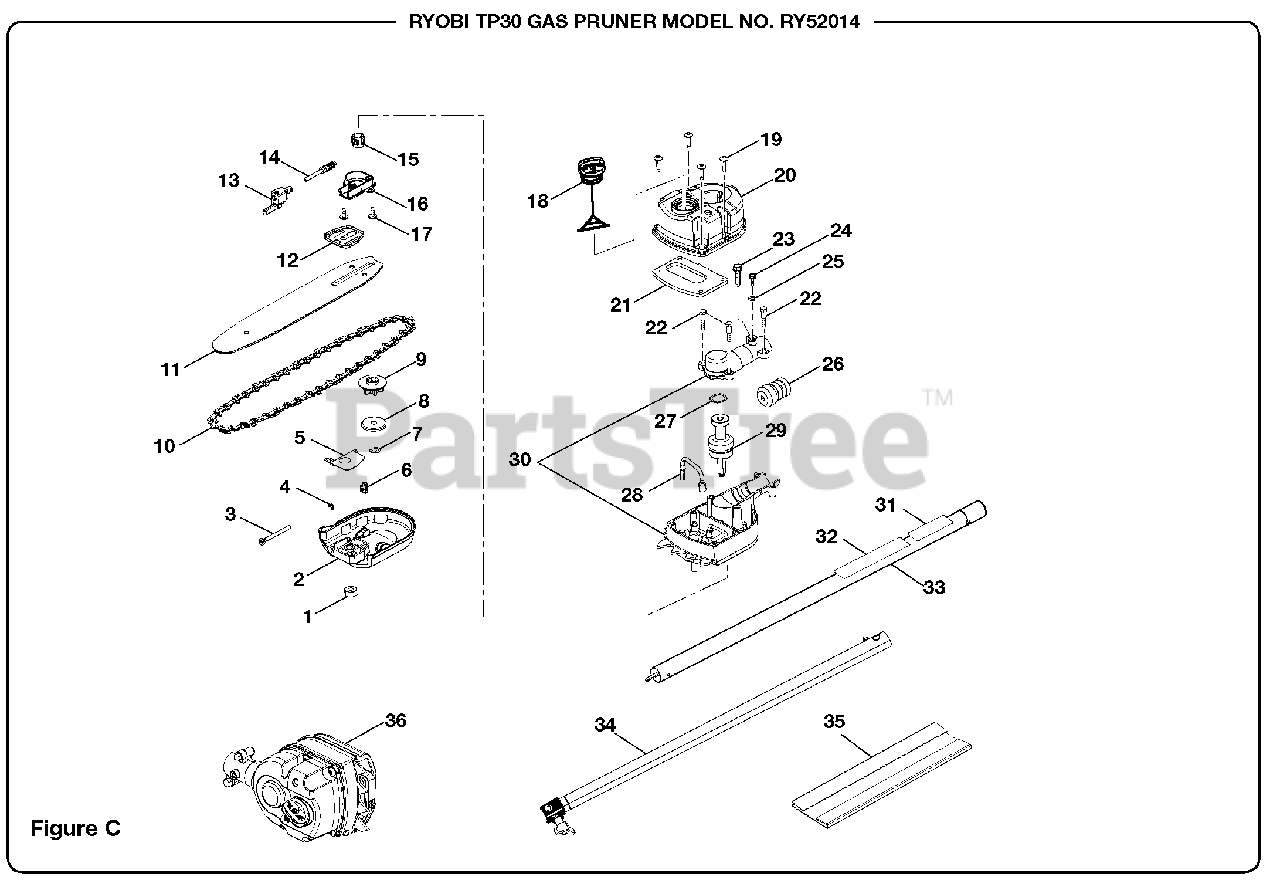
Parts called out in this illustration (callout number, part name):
1	Hex Nut (M8)
2	Bar Clamp Assembly
3	Guide Bar Adjustment Screw (M5 X 50 Mm)
4	Retaining Ring (4 Mm)
5	Guide Bar Plate
6	Guide Bar Adjusting Pin (M5)
7	E-Ring (6 Mm)
8	Cupped Washer
9	Sprocket
10	Chain (3/8, .043, 10)
11	Guide Bar
12	Bar Pad Plate
13	Oil Pump Seal Assembly
14	Oil Pinion Gear & Plunger
15	Worm Gear
16	Oil Pump Housing W/Cam Pin Assembly
17	Screw (M5 X 13 Mm)
18	Oil Cap With Retainer (Pkg.)
19	Screw (M5 X 18 Mm)
20	Oil Tank Cover Assembly
21	Oil Cover Gasket
22	Screw (M5 X 25 Mm, Shoulder Screw)
23	Screw (M5 X 25 Mm)
24	Screw (M5 X 15 Mm)
25	Spring Washer (M5)
26	Pinion Gear Assembly
27	Wavy Washer
28	Pick-Up Tube Assembly
29	Output Shaft Assembly
30	Gear Case And Cover Assembly
31	Expand-It Label
32	Warning Label
33	Pruner Boom Assembly (Includes Key. Nos. 31 And 32)
34	Intermediate Boom Assembly
35	Blade Cover
36	Pruner Gear Head (Includes Key. Nos. 1-9 And 12-30)
